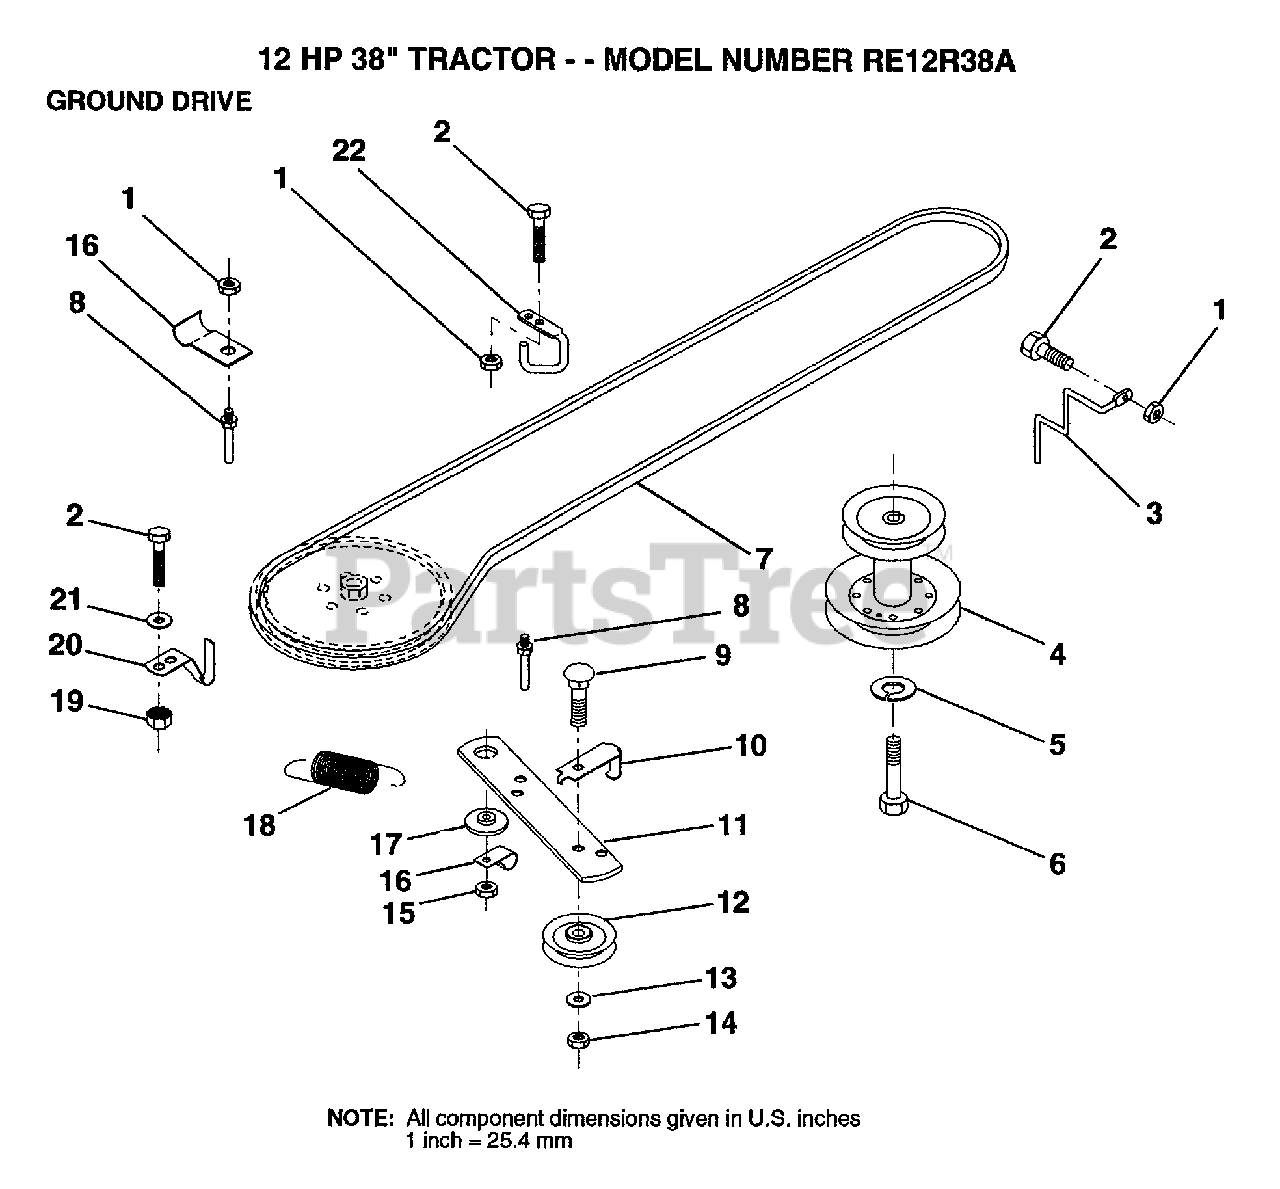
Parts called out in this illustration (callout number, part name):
2	BOLT
3	KEEPER MWR DR BLT
5	LOCKWASHER
6	BOLT
7	BELT
9	BOLT
10	KEEP,IDLER DR BEL
13	WASHER
14	LOCKNUT
16	CLIP,INSULATOR
21	WASHER
22	KEEPER,FRA DR BEL
